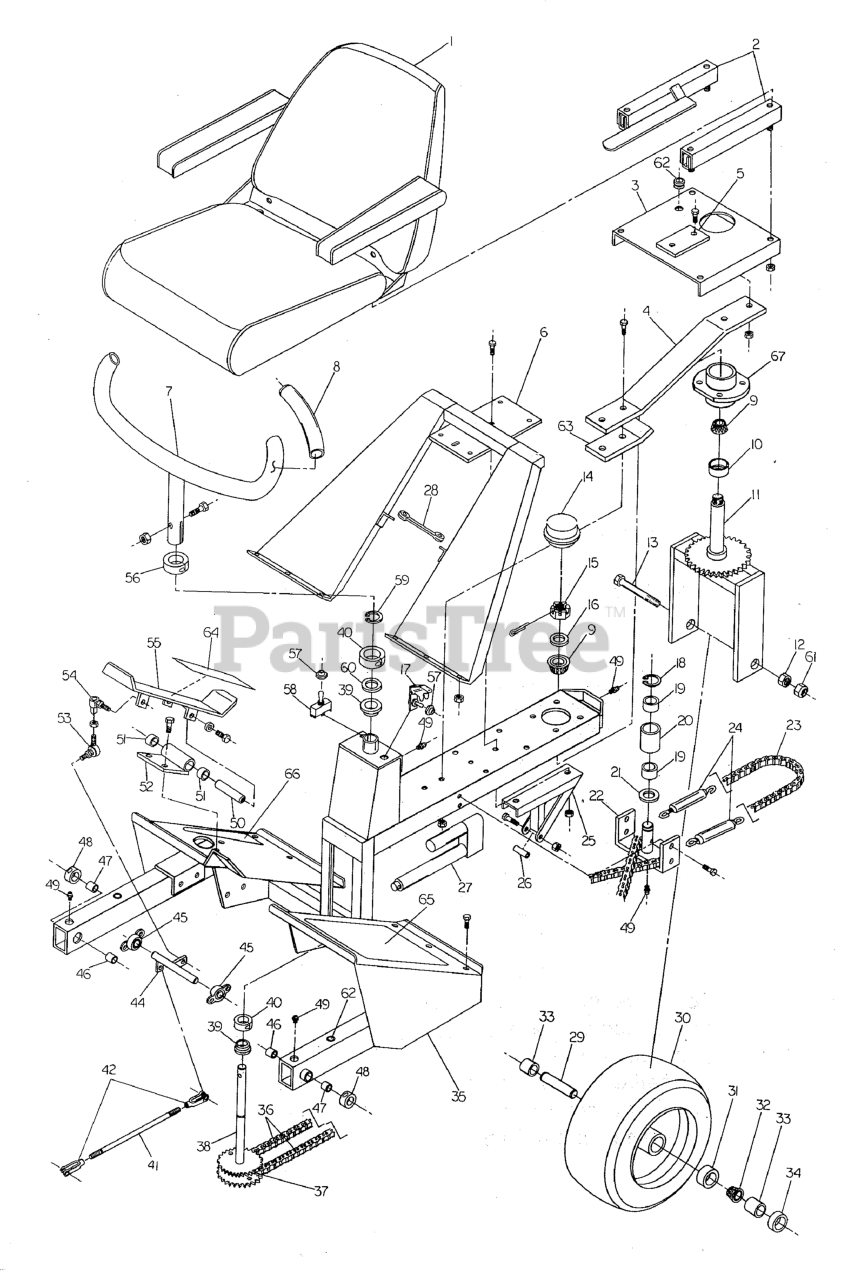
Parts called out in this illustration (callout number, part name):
1	SEAT, Black & Silver, Complete
1	CUSHION, BACK
1	CUSHION, BOTTOM
1	ARM REST, RH
1	ARM REST, LH
2	SEAT ADJUSTER RAILS (set of 2)
3	PLATE, Seat
4	SEAT SPRING
5	SUPPORT, Seat Plate
6	Rider Frame Support
7	STEERING HANDLE
8	GRIP, Foam
9	BEARING, Tapered Roller
10	SEAL, GREASE
11	MOUNT, Steering Tire
11	Steering Wheel Mount
12	NUT, 5/8-11 Hex
13	BOLT, 5/8-11 x 9-1/2
13	Axle Bolt
14	CAP
15	NUT, 3/4-16 Hex Slotted
16	WASHER, 3/4 SAE
17	Toggle Switch
17	Switch Guard
18	SNAP RING, External
19	BUSHING, Brass
20	CHAIN ROLLER
22	Chain Roller Mount
23	CHAIN, #40 Roller, 36 Links
24	TURNBUCKLE
25	Actuator Mount
26	Actuator Spacer
27	Electric Actuator
28	RUBBER STRAP
29	STEERING TIRE AXLE
29	Steering Tire Axle
30	WHEEL & TIRE ASSEMBLY, 18 x 7.5 x 8, White, Complete
30	TIRE & WHEEL ASSEMBLY, 18 X 8.5 X 8
30	HUB, Steering
30	SPACER, 1.00 x 1.25 x 3.81
30	SPACER, 1.00 x 1.25 x 1.81
30	LUG NUT, 1/2-20
30	SEAL, GREASE
31	BEARING CUP
32	BEARING, Tapered Roller
33	SPACER, 1.01 X 1.25 X 2.06
34	GREASE SEAL
35	Rider Frame Support
36	CHAIN, #40 Roller, 31 Links
37	CONNECTOR, #40 Chain Link
38	SHAFT, Steering Sprocket
39	BUSHING, Flange
40	COLLAR, 1-1/4" Split
41	Linkage Rod
42	CLEVIS, 5/16-24, Plastic
44	Foot Pedal Bell Crank
45	BEARING, Flange
46	BUSHING
47	BUSHING, Brass
48	COLLAR, 3/4" Split
49	GREASE FITTING
50	SHAFT, Pedal Pivot
51	BUSHING, Brass
52	FOOT PEDAL PIVOT MOUNT, Complete
53	BALL JOINT, 3/8-24 Male, Studded
54	BALL JOINT, 3/8" Female Studded
55	FOOT CONTROL PEDAL
56	COLLAR, 1" Split
57	Toggle Boot
58	Toggle Switch
59	Snap Ring
60	SHIM
61	NUT, 5/8-11 Hex Side Lock
62	GROMMET, 1/2"
63	SUPPORT, Seat Spring
64	SAFETY WALK
65	SAFETY WALK
66	SAFETY WALK
67	HUB, Steering
